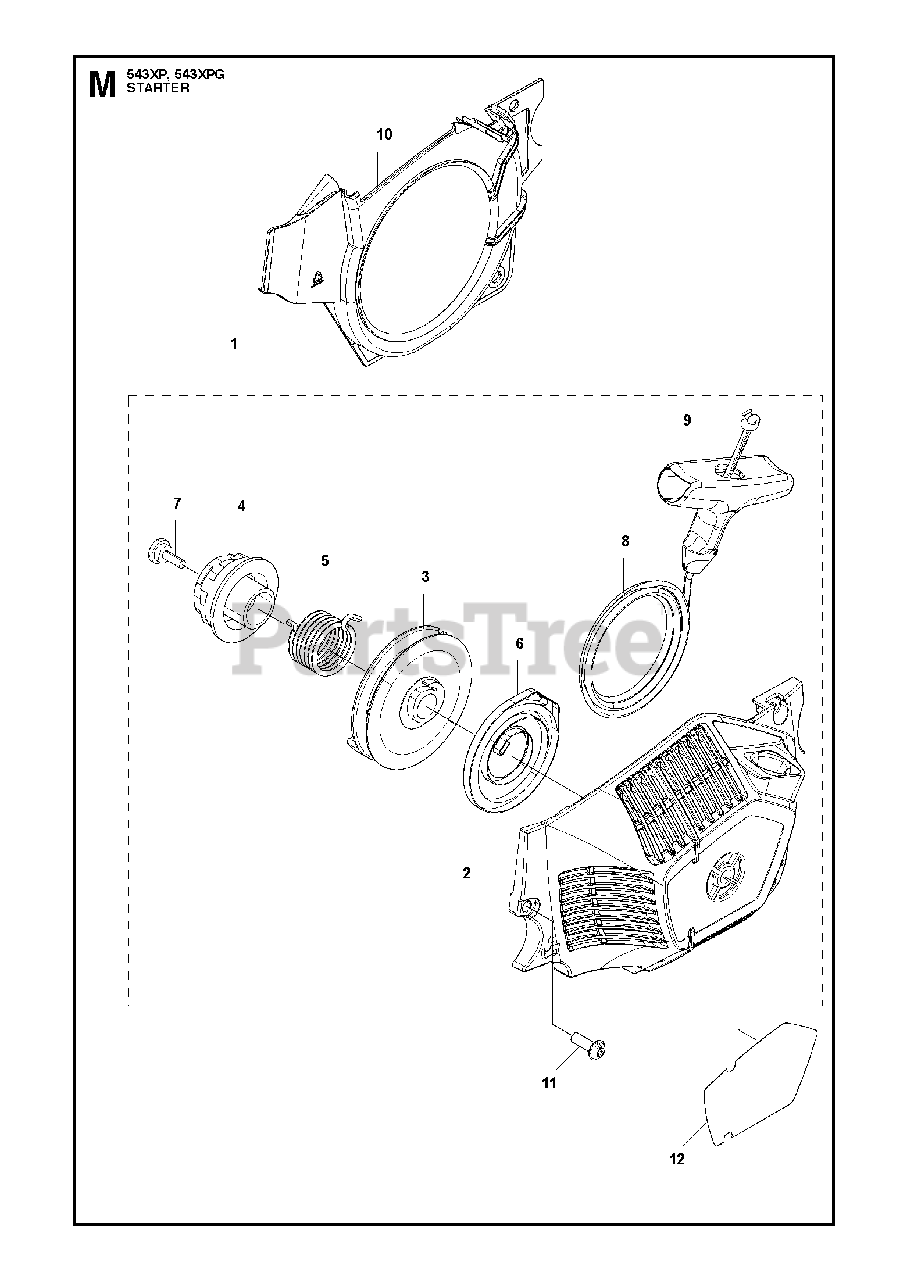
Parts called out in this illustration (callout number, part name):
1	STARTER ASSY XC25
2	CASE COMP XC25
3	REEL
4	STARTER PULLEY CAM
5	SPRING
6	SPRING CASSETTE ASSY OLD P/N
7	SCREW
8	ROPE
9	HANDLE
10	AIR BAFFLE
11	SCREW M5 X 14
12	DECAL
